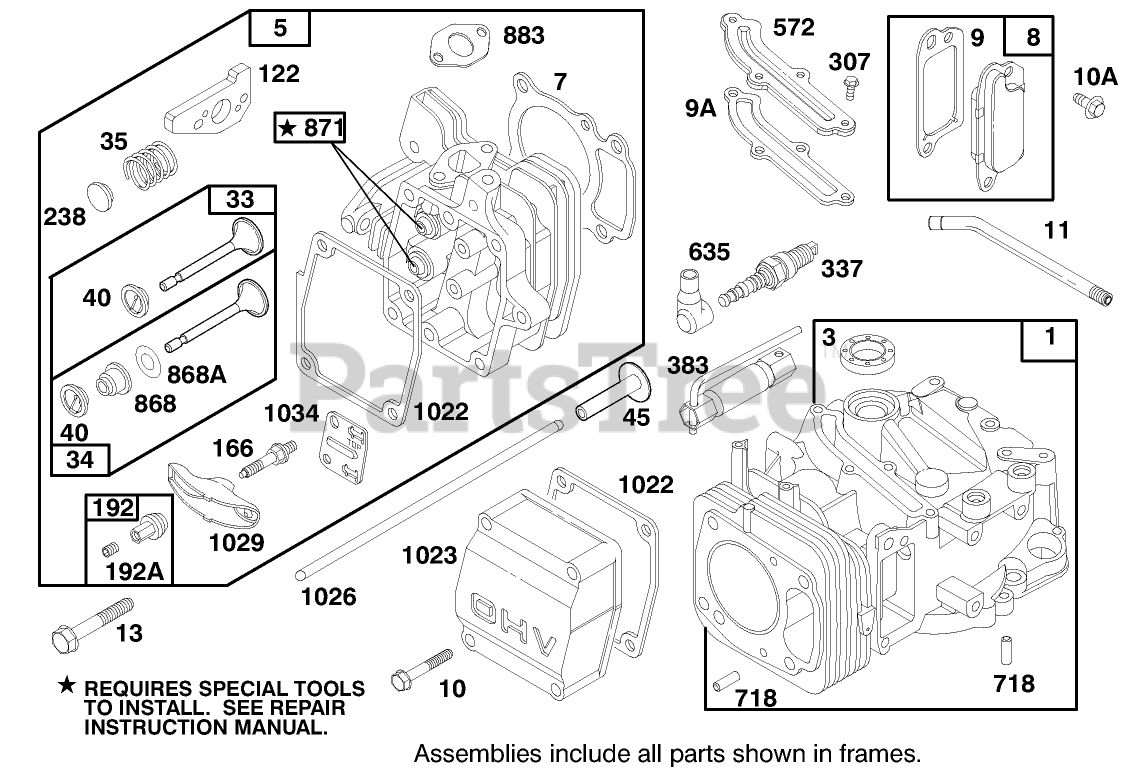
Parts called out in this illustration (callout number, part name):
1	CYLINDER ASSEMBLY
7	CYLINDER HEAD GASKET
10	HEX HEAD SCREW
13	PLUG - PIPE
33	EXHAUST VALVE
34	INTAKE VALVE
35	VALVE SPRING
45	VALVE TAPPET
122	ADAPTER ASSEMBLY
166	ROCKER ARM STUD
307	SCREW - SEM
337	PLUG-SPARK
383	WRENCH-SPARK PLUG
635	SPARK PLUG ELBOW
868	ASM - VALVE SEAL
871	Bushing-Guide
1022	ROCKER COVER GASKET
1026	PUSH ROD
1029	ROCKER ARM
1034	PUSH ROD GUIDE
